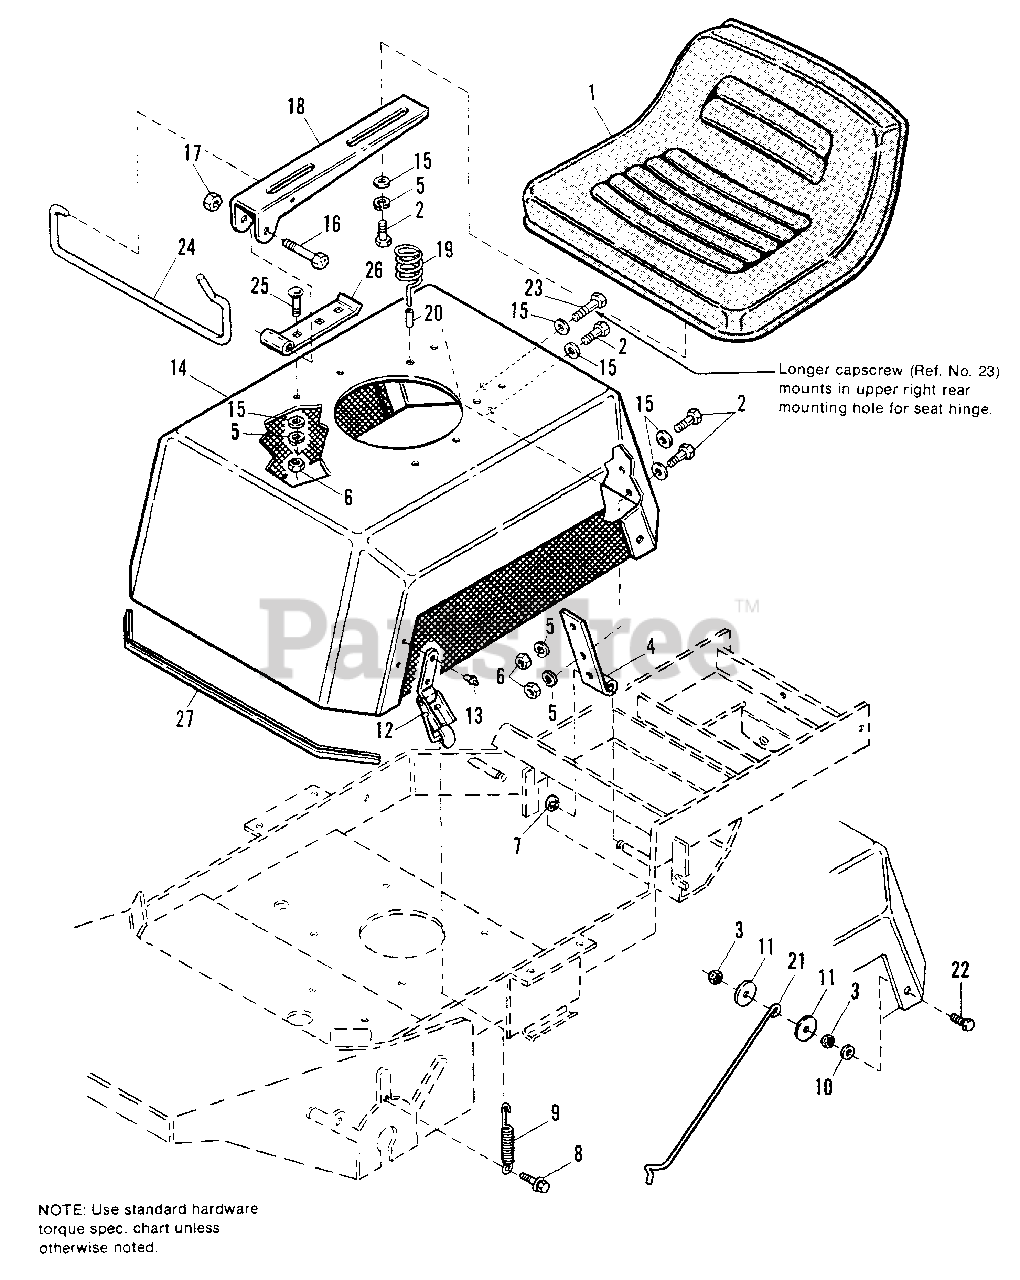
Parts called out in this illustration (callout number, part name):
2	CAPSCREW, 5/16-18 x 3/4
3	NUT, Hex Centerlock, 1/4-20
4	HINGE, Seat Deck
5	LOCKWASHER, 5/16
6	NUT, Hex, 5/16-18
7	RING, Retaining
8	SCREW, Taptite, 5/16-18 x 1/2
9	SPRING, Latch
10	WASHER
11	WASHER, 1/4 x 1-1/4
12	LATCH, Seat, Pull Tight
13	RIVET, Seat Latch
15	WASHER, Flat, 5/16
16	CAPSCREW, 3/8-16 x 2
17	NUT, Hex Lock, 3/8-16
18	HINGE, Upper, Seat
19	SPRING, Seat
20	COVER, Spring
21	ROD, Seat Deck
22	CAPSCREW, 1/4-20 x 1
23	CAPSCREW, 5/16-18 x 1
24	LATCH, Seat
25	CARRIAGE BOLT, 5/16-18 x 3/4
26	HINGE, Lower Seat
27	MOLDING, Deck
